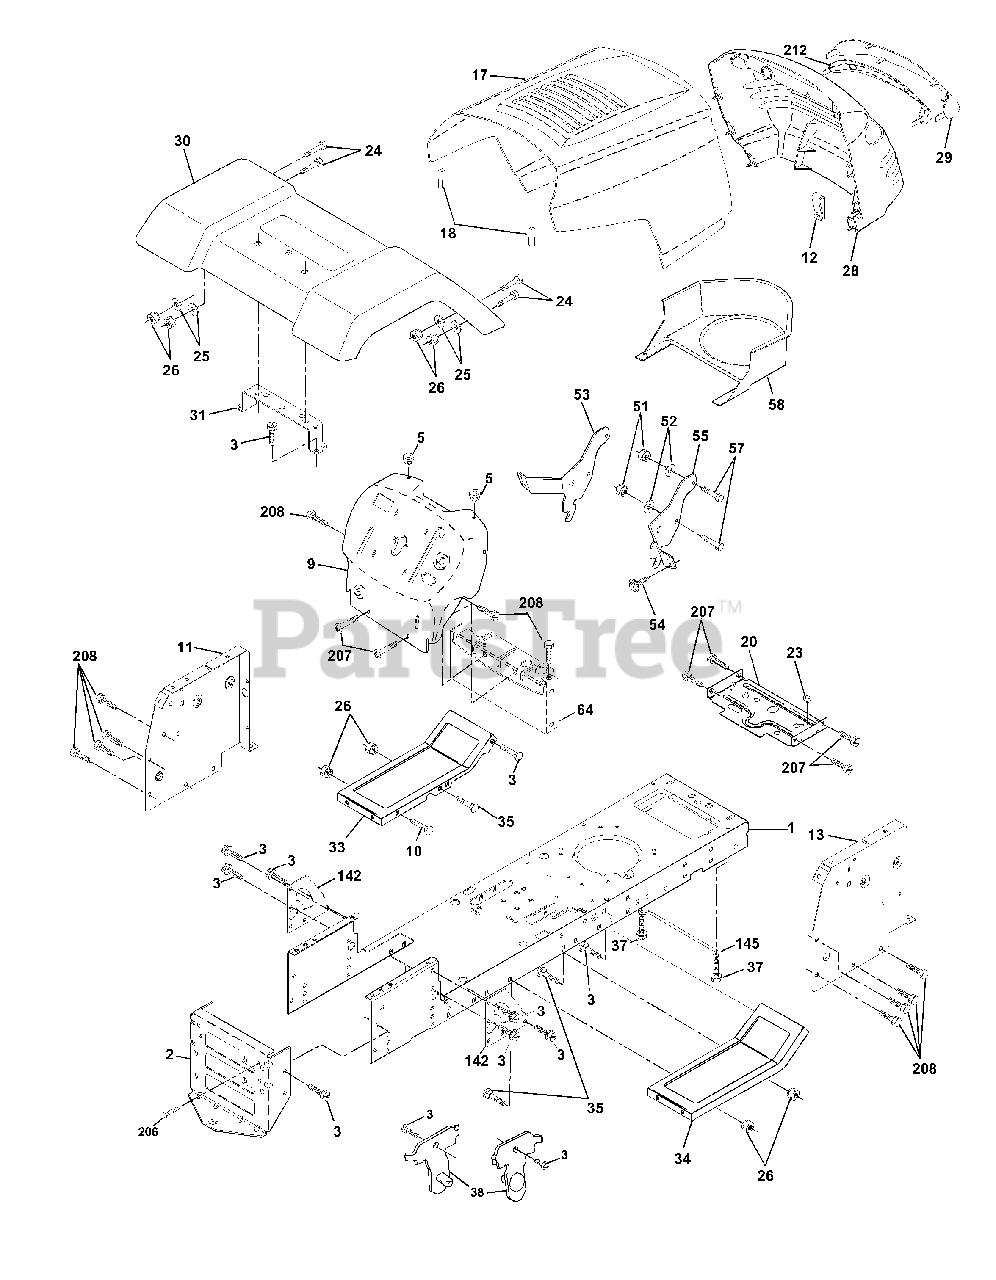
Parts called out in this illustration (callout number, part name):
1	Chassis
2	Drawbar
3	Screw 3/8-16 X .75
5	Bumper Hood/Dash
9	Dash P/L
10	Bolt Carriage 3/8-16 x 1
11	Panel Dash Lh
12	Clip Tinnerman
13	Panel Dash Rh
17	Hood LT/PL
18	Bumper Hood
20	Plate Mtg Battery Fuel Tank Fr
23	Bushing
24	Bolt Fin Hex 3/8-16 x 1 Gr 5
25	Washer 13/32 X 13/16 X 12 Ga
26	Nut Lock Hex W/Ins 3/8-16 Unc
28	Grille/Lens Asm
29	Lens LT/PL
30	Fender Footrest STLT Pnt
31	Bracket Fender
33	Footrest Pnt Lh
34	Footrest Pnt Rh
35	Bolt Rdhd Sht Sqnk 3/8-16 x 3/4
37	Screw Thdrol 6/16-18 x 1/2 TYT
38	Bracket Asm Pivot Mower Rear
51	Nut Lock Hex W/Ins 1/4-20
52	Washer 9/32 x 7/8 x 16 Ga.
53	Bracjet Grukke Lh
54	Screw Hex Wshd 8-18 x 7/8
55	Bracket Grille Rh
57	Bolt Hex 1/4-20 x 3/4
58	Duct Air
64	Dash Lower STLT
142	Plate Reinforcement STLT
145	Rod Pivot Chassis/Hood
206	Bolt Shoulder 5/16-18
207	Screw Thdrol 5/16-18 x 1/2
208	Screw Thdrol 3/8-16 x 1/2
212	Insert Lens Relect
